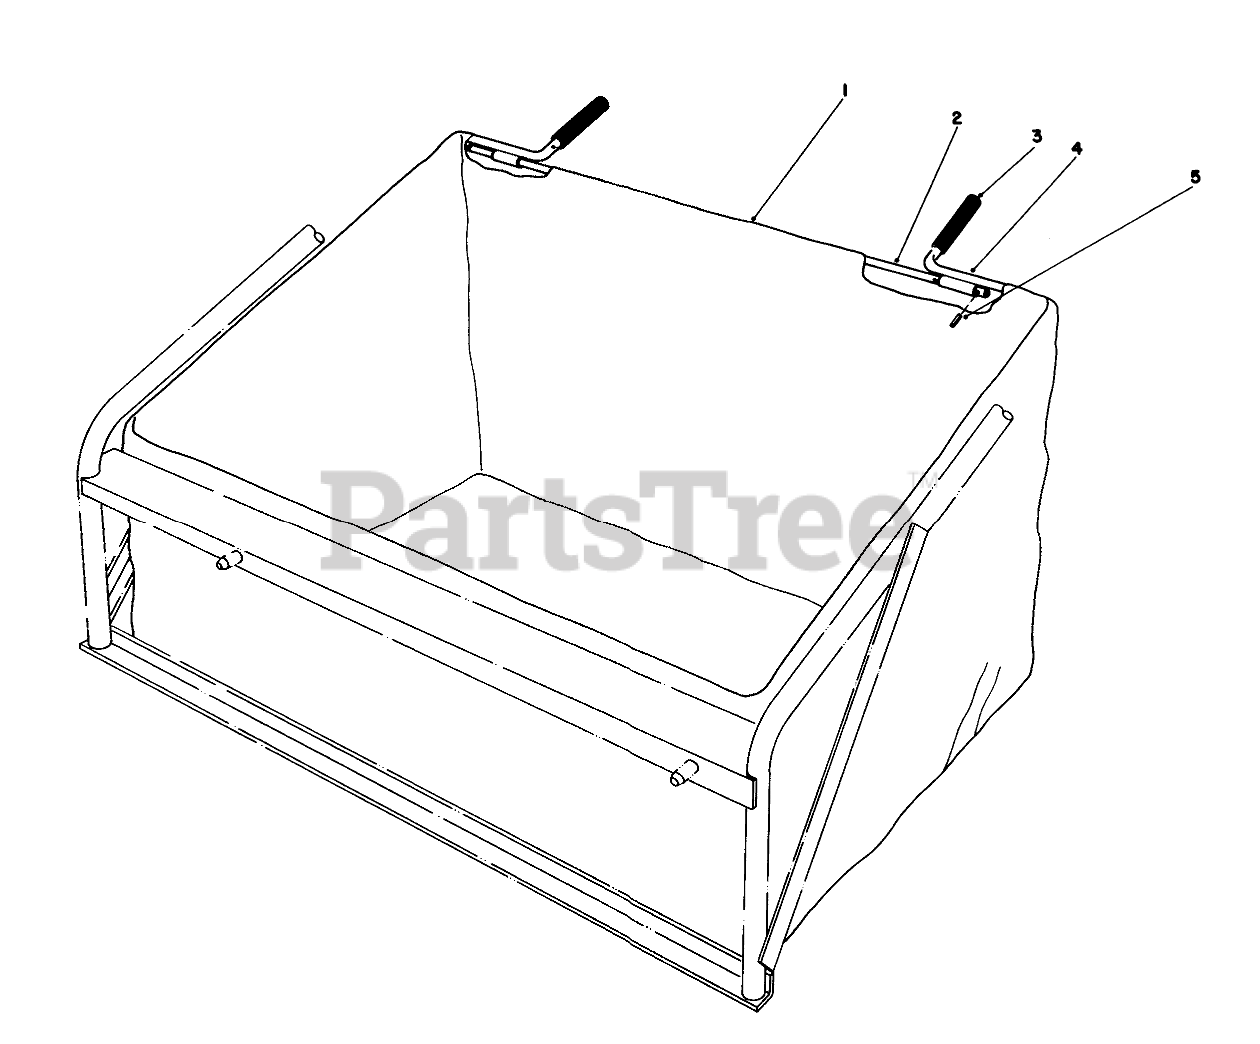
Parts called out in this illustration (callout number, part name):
1	Bag-Leaf Catcher
2	BAG FRAME ROD
3	BAG HANDLE GRIP
4	BAG FRAME WA B
5	PIN-ROLL
